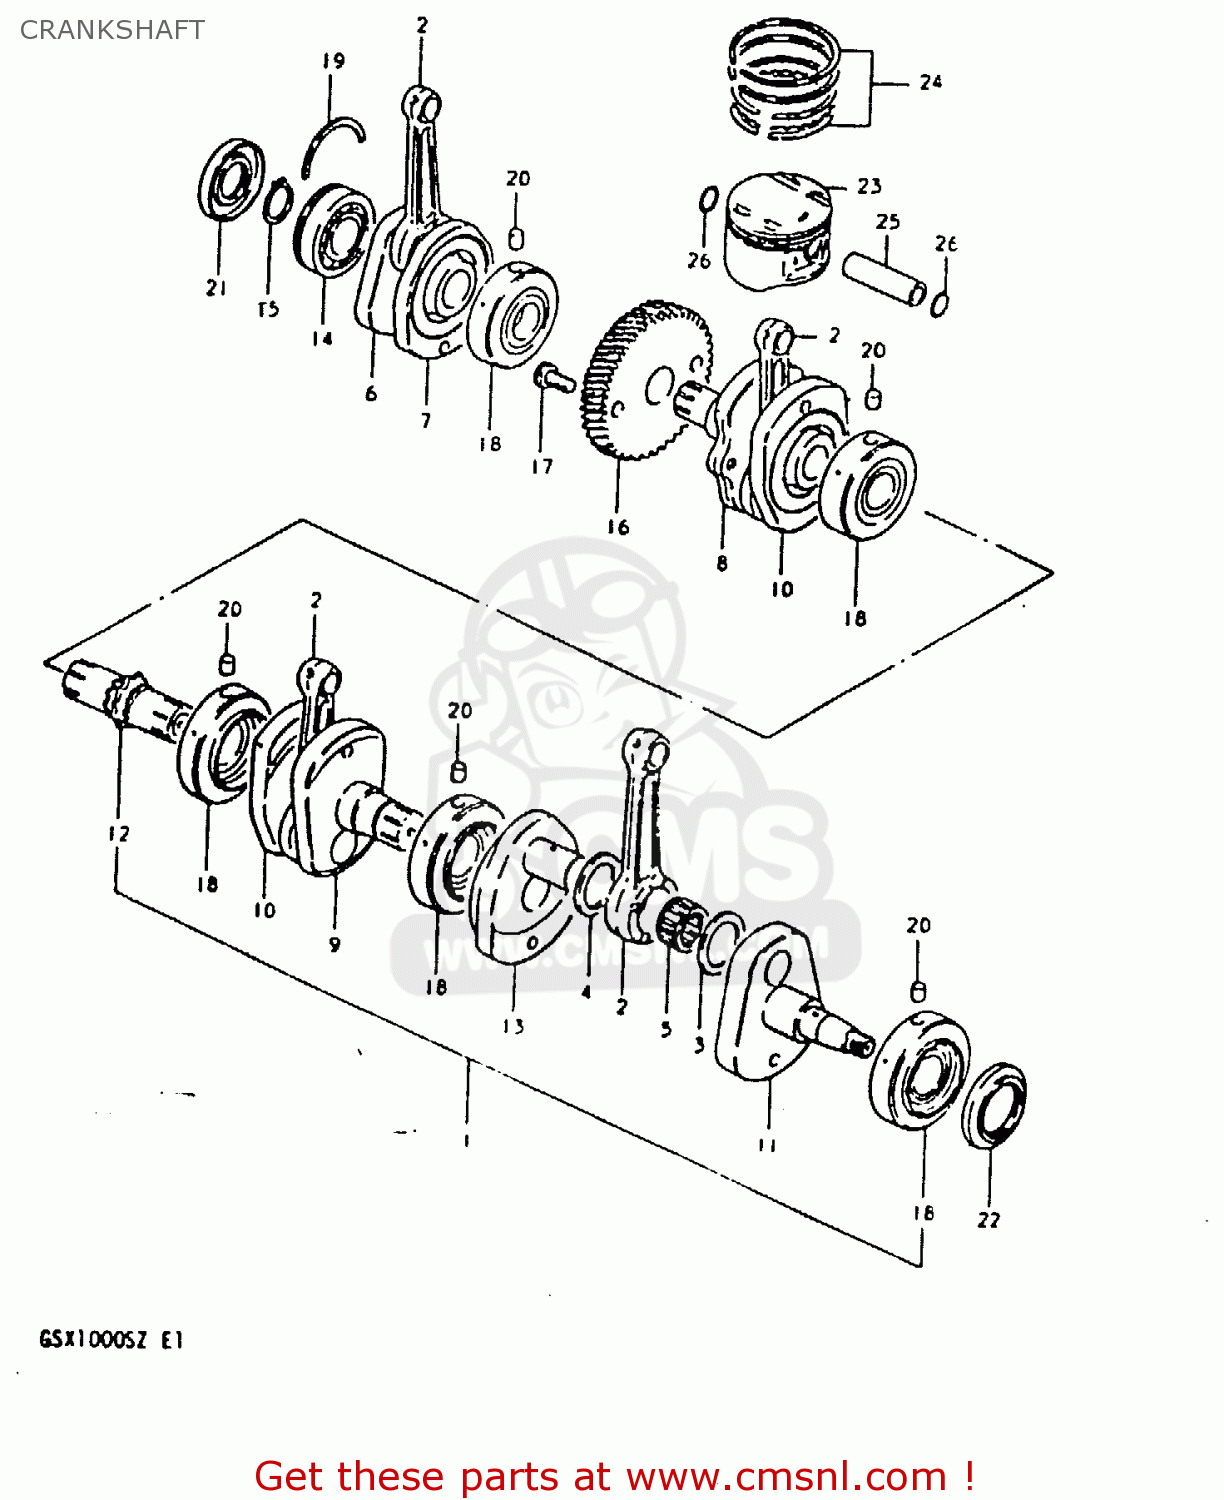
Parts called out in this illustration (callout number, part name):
1	CRANKSHAFT ASSY
2	ROD,CONNECTING
3	WASHER(31X48.5X1)
4	WASHER(31X48.5X2)
5	BEARING(31X39X21)
6	CRANKSHAFT,RIGHT
7	WEB,CRANK
8	CRANKSHAFT
9	CRANKSHAFT,MIDDLE,LEFT
10	WEB,CRANK,MIDDLE
11	CRANKSHAFT,LEFT
12	SHAFT,TIMING CHAIN DRIVE
13	WEB,CRANK,LEFT
14	BEARING(30X72X19)
15	CIRCLIP,30MM
16	GEAR,PRIMARY DRIVE
17	BOLT
18	BEARING
19	C RING
20	PIN
21	SEAL,OIL(30X72X11)
22	SEAL,OIL(47.3X60X6.5)
23	PISTON (STD)
24	RING SET,PISTON
25	PIN,PISTON
26	CIRCLIP,PISTON PIN
